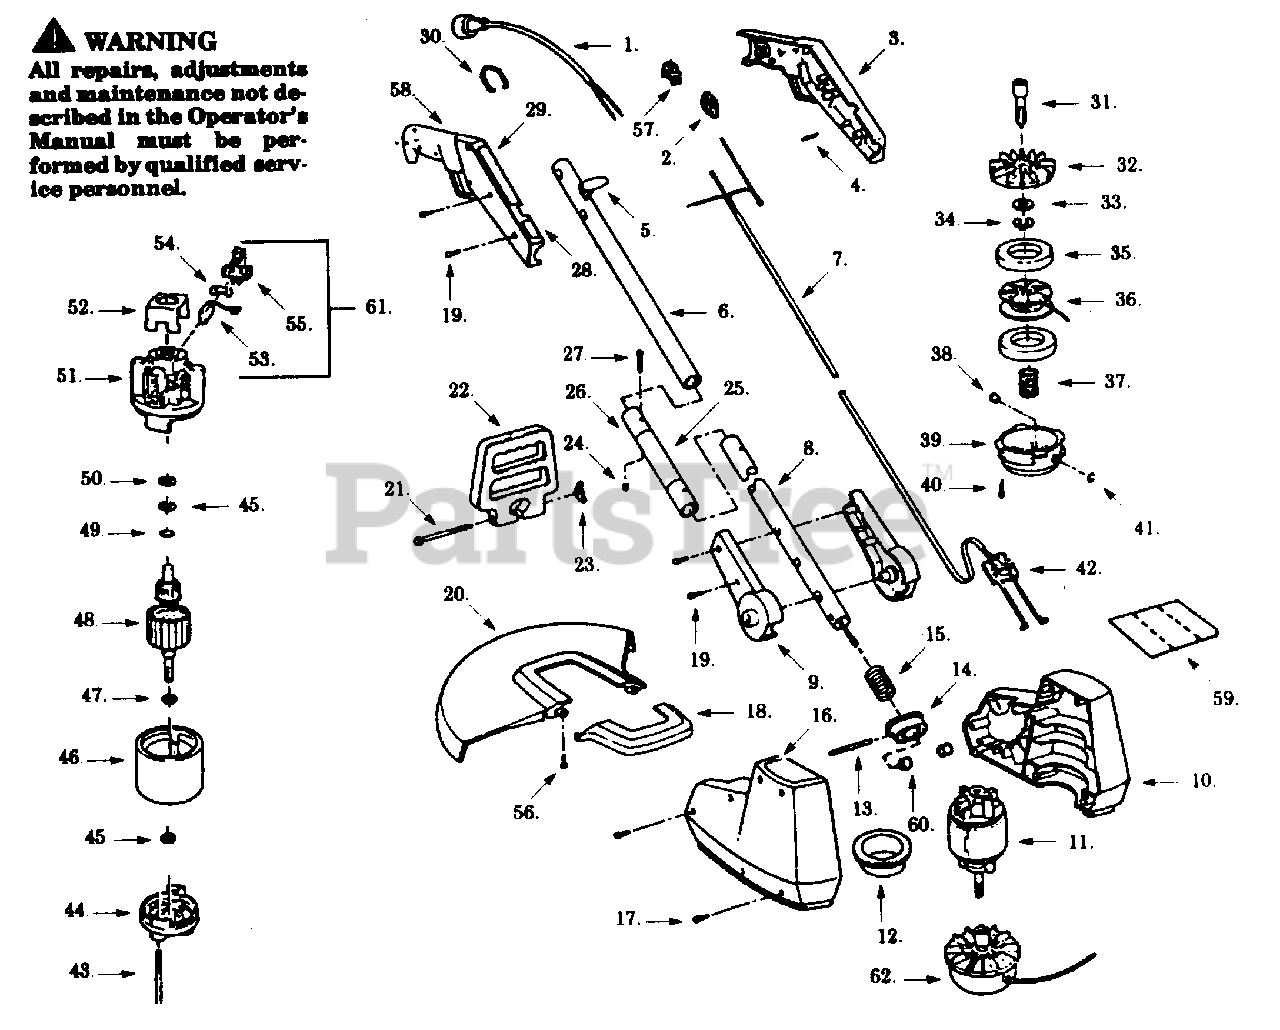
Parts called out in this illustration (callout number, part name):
1	Power Cord
2	Trigger Switch
3	R.H./L.H. Handle
4	Hinge Pin
5	Cable & Lever Ass'y.
6	Upper Tube
8	Lower Tube
9	R.H./L.H. Pivot
10	R.H./L.H. Housing
12	Air Baffle
13	Sleeve Pin
15	Sleeve Spring
16	Hsg. Top Label
18	Front Guard
20	Guard & Blade Ass'y.
22	Assist Handle
23	Wing Nut
24	Stop Nut
25	Warning Label (Not a serviceable part)
26	Outer Tube
28	Inch Cut Label (Not a serviceable part)
29	Handle Label (Not a serviceable part)
31	Drive Adapter
32	Rear Plate
34	Retaining Ring
35	Foam Pad
36	Spool & Line
39	Hub Ass'y.
40	Cotter pin
41	Wire Ring
42	P.C. Bridge
44	Endbell Ass'y. (Drive)
46	Field Ass'y.
47	Retaining Ring
48	Armature Ass'y.
49	Retaining Ring
51	Endbell Ass'y. (Brush)
52	Insulator
54	Brush Spring
55	Brush Holder
57	Power Switch
58	Torque Booster Label (Not a serviceable part)
59	Insulator Shield
60	Cable Sleeving
61	Brush Kit (Incl. 53,54,55)
62	Cutting Head Ass'y.
